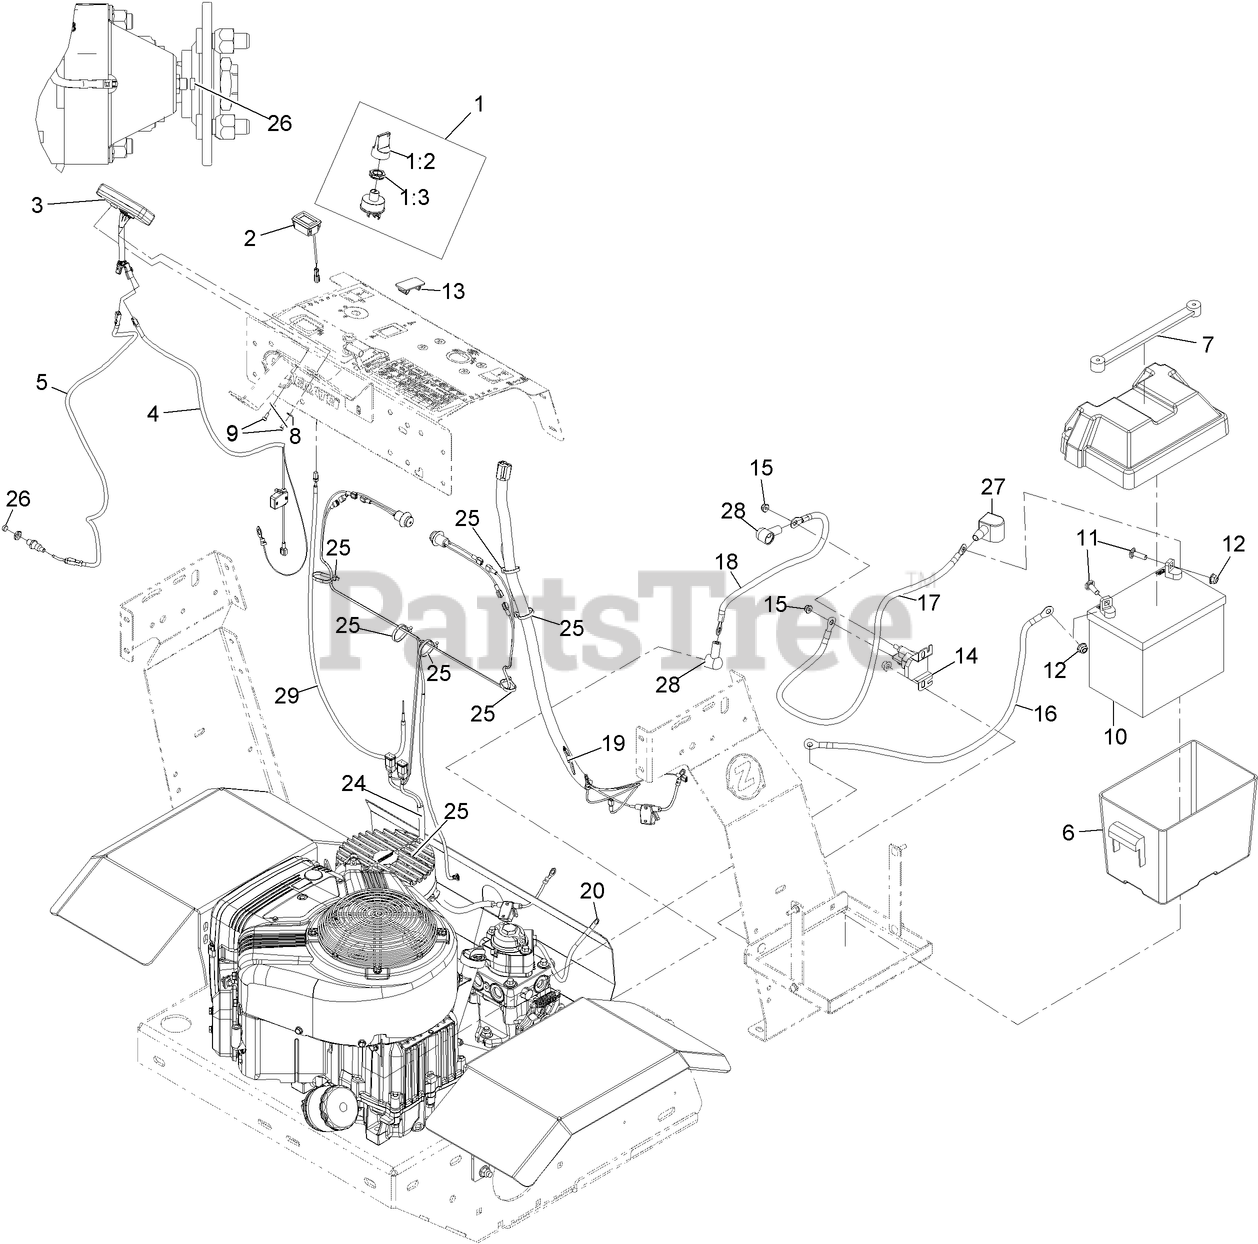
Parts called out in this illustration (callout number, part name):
1	ASM-SWITCH, KEY
1:2	KEY-UMBRELLA
1:3	NUT-SWITCH, KEY
2	METER-TACH/HOUR
3	HEAD ONLY, STRIKER
4	HARNESS-STRIKER
5	Cable-Trail Tech, Sensor
6	BATTERY BOX ASM
7	BUNGEE (TARP STRAP)
8	WASHER-FLAT
9	SCREW-HSH
10	Battery (340 CCA, Wet)
11	SCREW-CARR
12	NUT-HF, NI
13	PLUG-HOLE
14	Solenoid-Starter
16	CABLE-GROUND
17	28" RED BATTERY CABLE
18	CABLE-POSITIVE
19	WIRING HARNESS
20	WIRE-SOLENOID
24	HARNESS, KIT, THUMB SWITCH, ZP
25	TIE-CABLE
26	MAGNET, SPEEDOMETER
27	Insulator-Battery
28	INSULATOR-SOLENOID
29	WIRE-TACHOMETER
